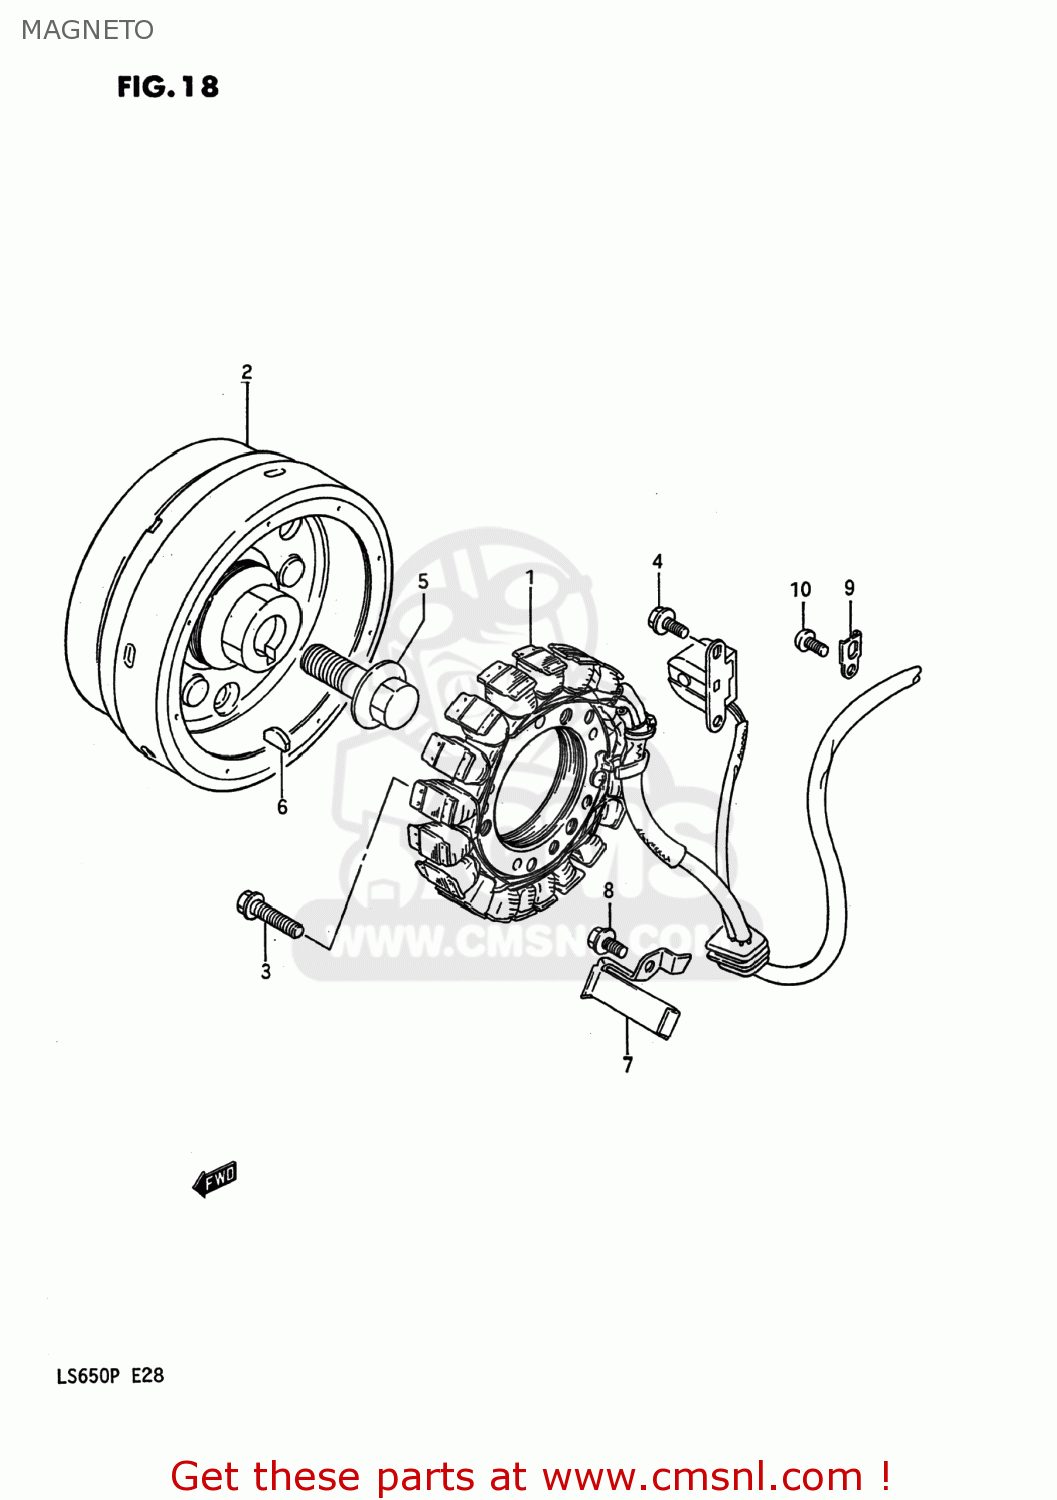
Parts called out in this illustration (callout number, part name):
1	STATOR ASSEMBLY
2	ROTOR,FLYWHEEL
3	BOLT
4	BOLT
5	BOLT(14X43)
6	KEY
7	CLAMP,MAGNETO LEAD WIRE NO.1
8	BOLT
9	CLAMP,GENERATOR LEAD WIRE
10	SCREW
